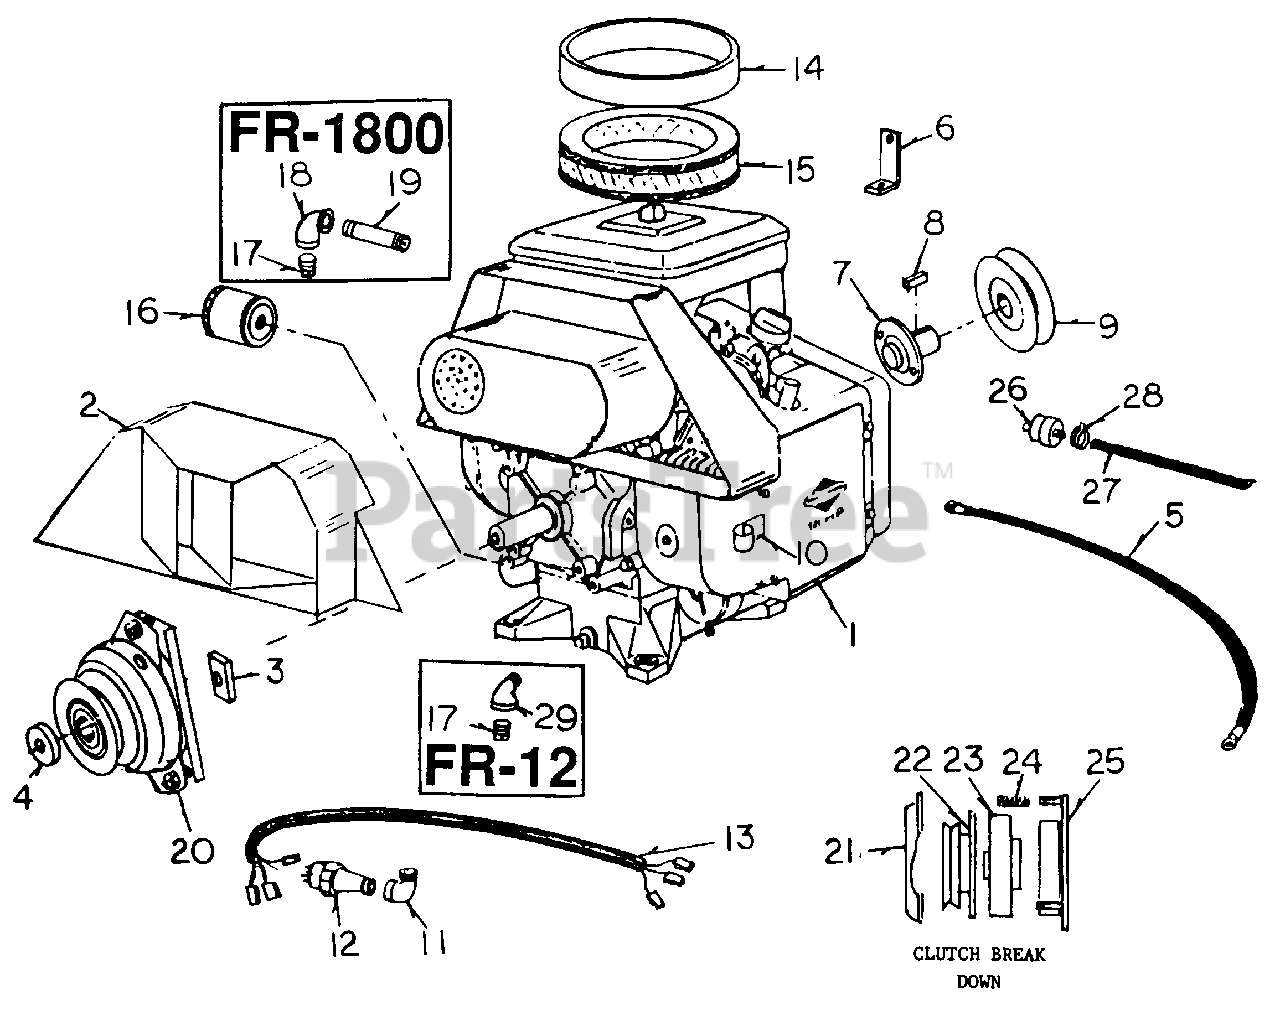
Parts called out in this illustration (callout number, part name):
1	Briggs & Stratton Twin
4	Clutch Retainer Washer
6	Wire Stand Off
8	Key Stock, 1/4"
10	Starter Cable Retainer
11	Street Elbow, 1/8"
12	Oil Sending Unit
13	Wire Harness
14	Pre Cleaner
15	Air Cleaner Cartridge
16	Oil Filter
18	Elbow, 3/8"
19	Nipple, 3/8"
20	Clutch
22	Clutch Armature
23	Clutch Rotor
24	Spring & Nut Set
25	Clutch Coil
26	Fuel Filter
28	Fuel Line Clamp
29	Street Elbow
